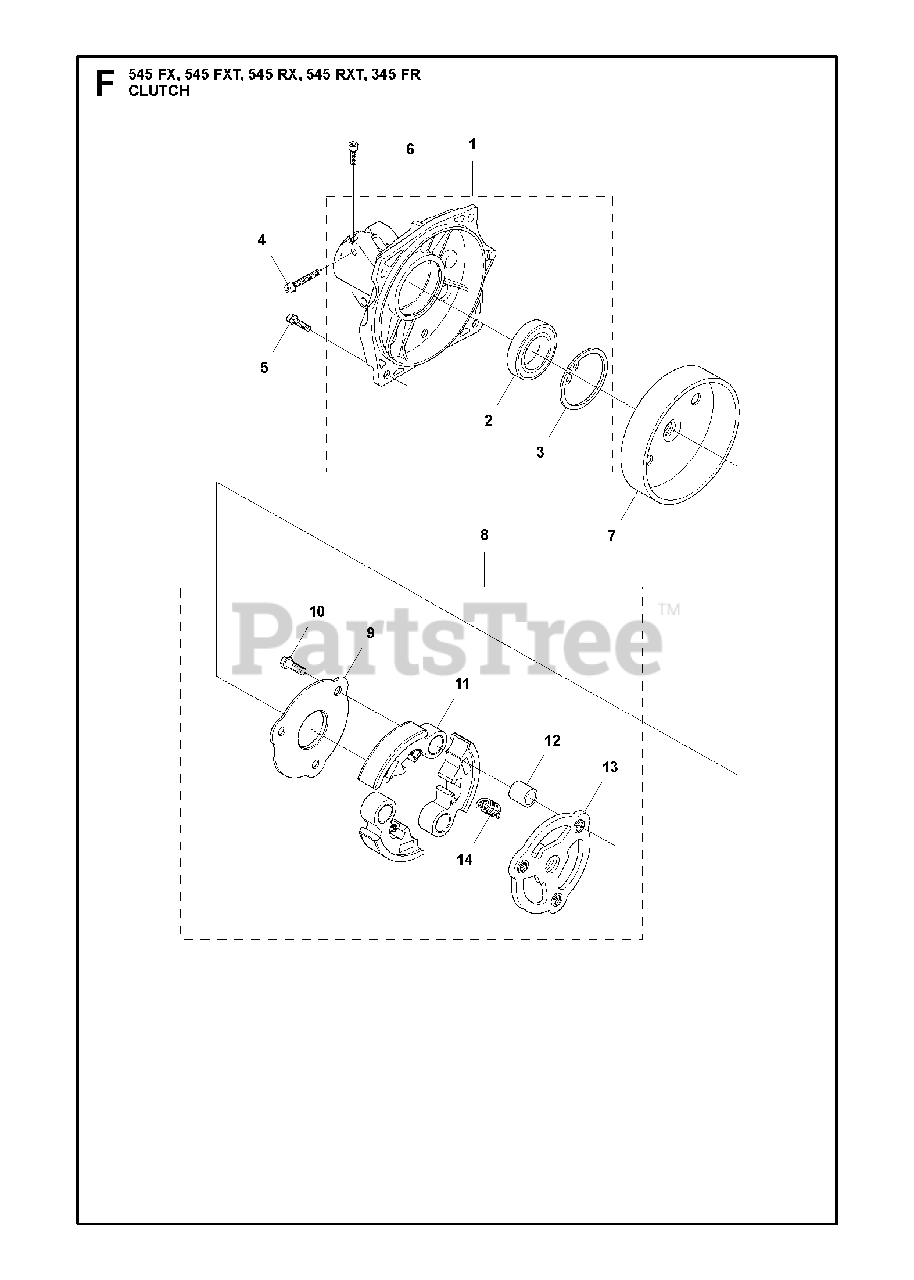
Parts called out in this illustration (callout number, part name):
1	COVER, CLUTCH
2	BALL BEARING 6202-2RS1
3	RETAINING RING SGH 35
6	SCREW MC6LS 5X12
7	CLUTCH DRUM ASSM.
8	CLUTCH CPL
9	WASHER
10	SCREW
11	CLUTCH
12	BUSHING
13	HUB
14	CLUTCH SPRING
